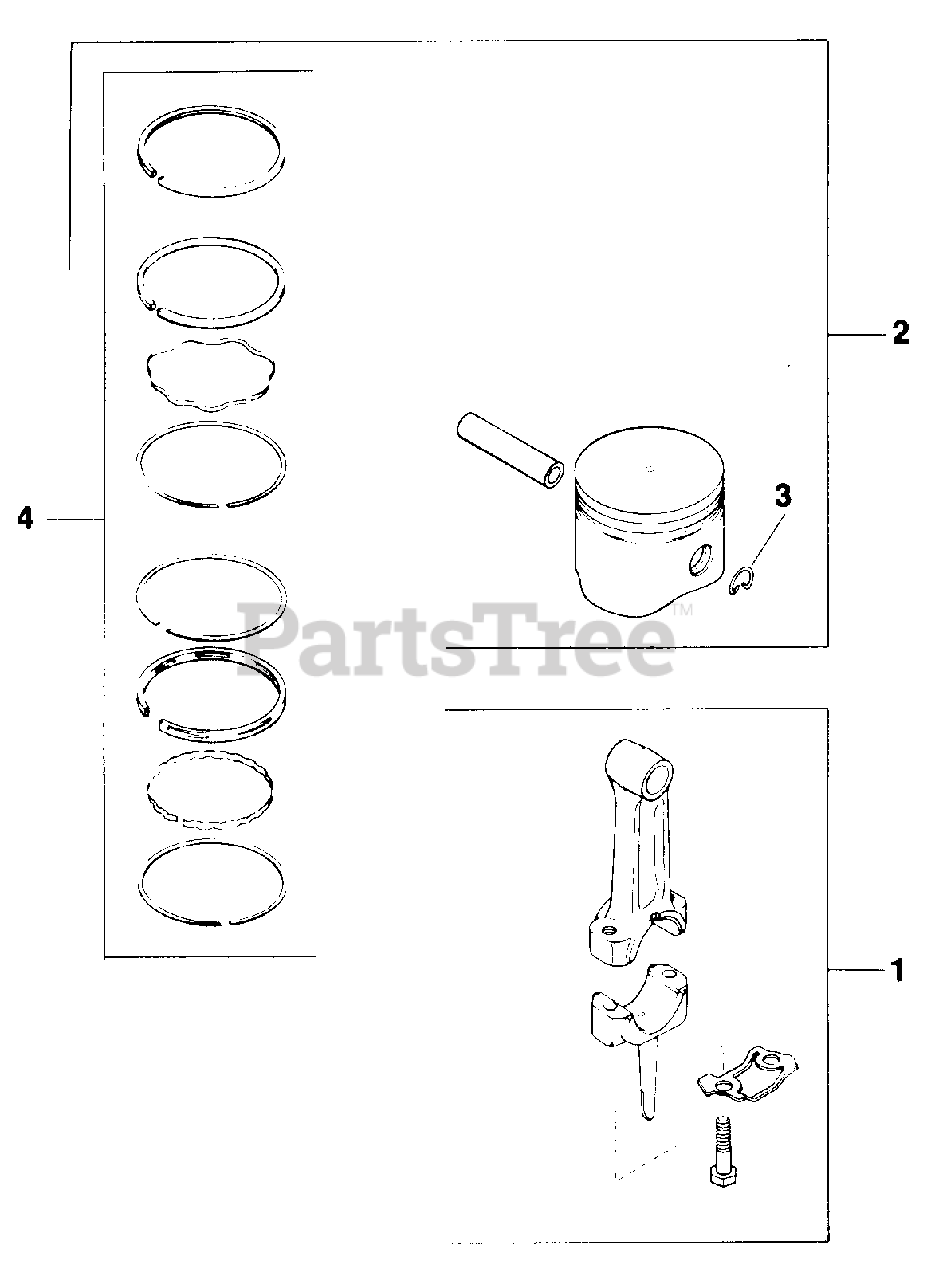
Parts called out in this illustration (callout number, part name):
1	Connecting Rod (Std.)
2	Piston w/Ring Set (Std.)
3	Retainer, Piston Pin
4	Ring Set (Std. & .003)
